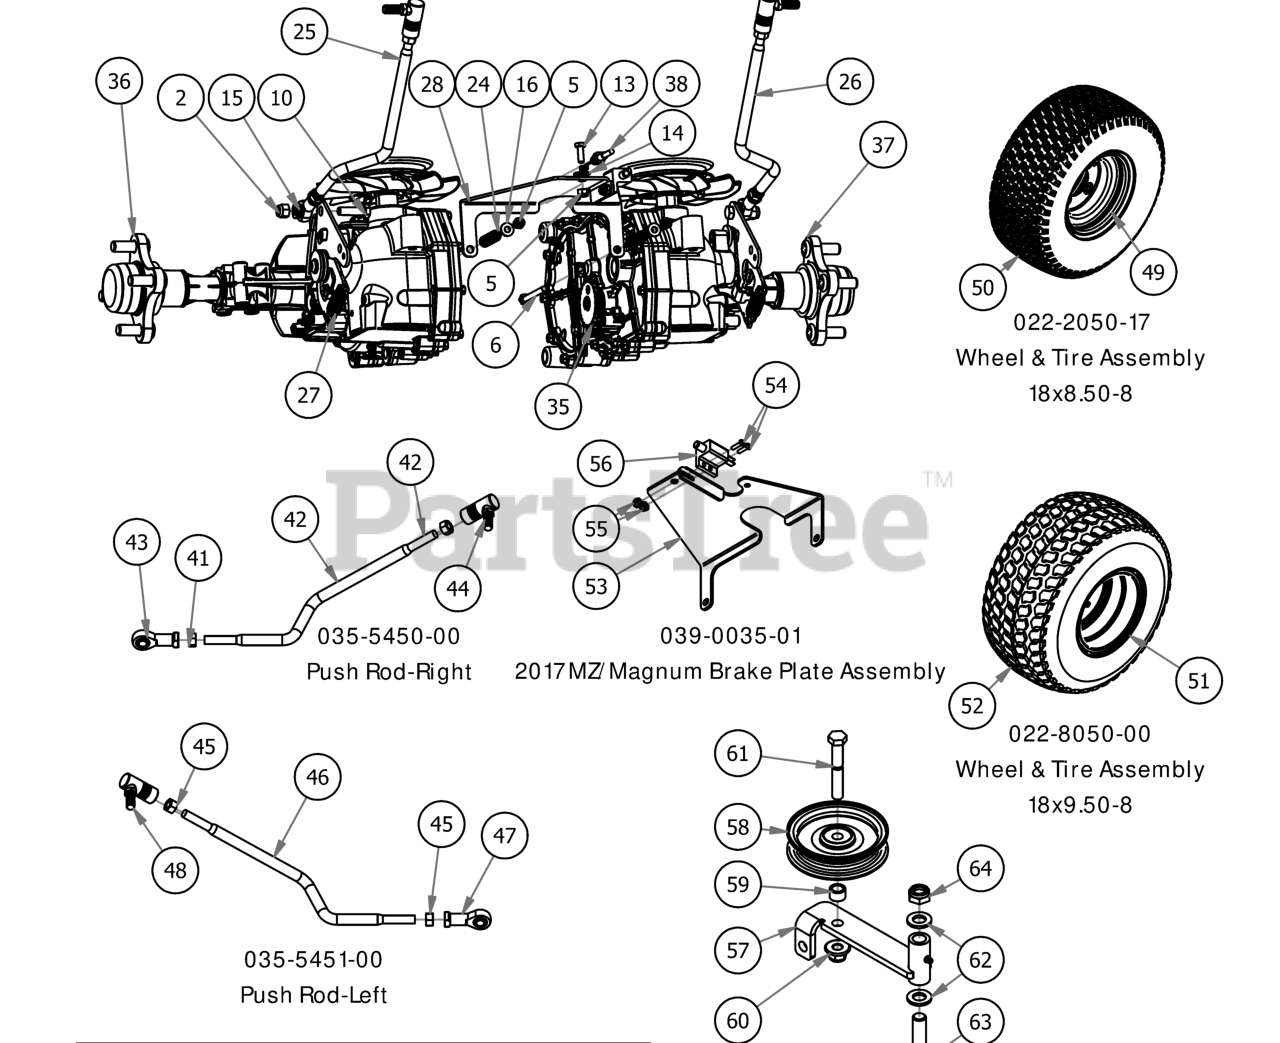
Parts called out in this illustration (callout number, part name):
2	3/8 Nylock Nut
5	1/4 Nylock Nut
6	1/4-20 x2-1/2 Gr2 hex C/s zinc
10	3/8" x 1 1/4" Hex Bolt
13	1/4" x 3/4" Hex Bolt
14	.390 x .750 x .062 Nylon Washer
15	3/8" Lock Washer
16	1/4" Flat Washer
24	Brake Spring
25	Push Rod-Right
26	Push Rod-Left
27	Gold Transaxle Spring
28	2017 MZ/Magnum Brake Plate Assembly
35	MZ Brake Cog Kit (Sold as Kit Only)
36	2017 MZ Right Transaxle
37	2017 MZ Left Transaxle
38	MZ Brake Cable
41	3/8" Fine Threaded Jam Nut
42	Push Rod - Right
43	Spherical Rod End - Outlaw
44	Quick Release Ball Joint
45	3/8" Fine Threaded Jam Nut
46	Push Rod - Left
47	Spherical Rod End - Outlaw
48	Quick Release Ball Joint
49	Wheel, 8.50-8, 42" MZ
50	Tire, 18x8.50-8, 42" MZ
51	rear rim for a 48in
52	18 x 9.50 - 8 Tire Only MZ
53	2017 MZ Brake Lock Bracket
54	10-24 X 5/8 BS Button Head Bolt
55	#10 Nylock Nut
56	Safety Switch
57	Pump Idler Bracket
58	4 3/4" Idler Pulley
59	1/2 x 1/2 Spacer
60	1/2-13 Nylon Flange Nut
61	1/2 x 2-3/4 Hex Bolt
62	.630 ID Plastic Washer
63	5/8" x 4" Hex Bolt
64	5/8" Nylock (1/2 Jam)
